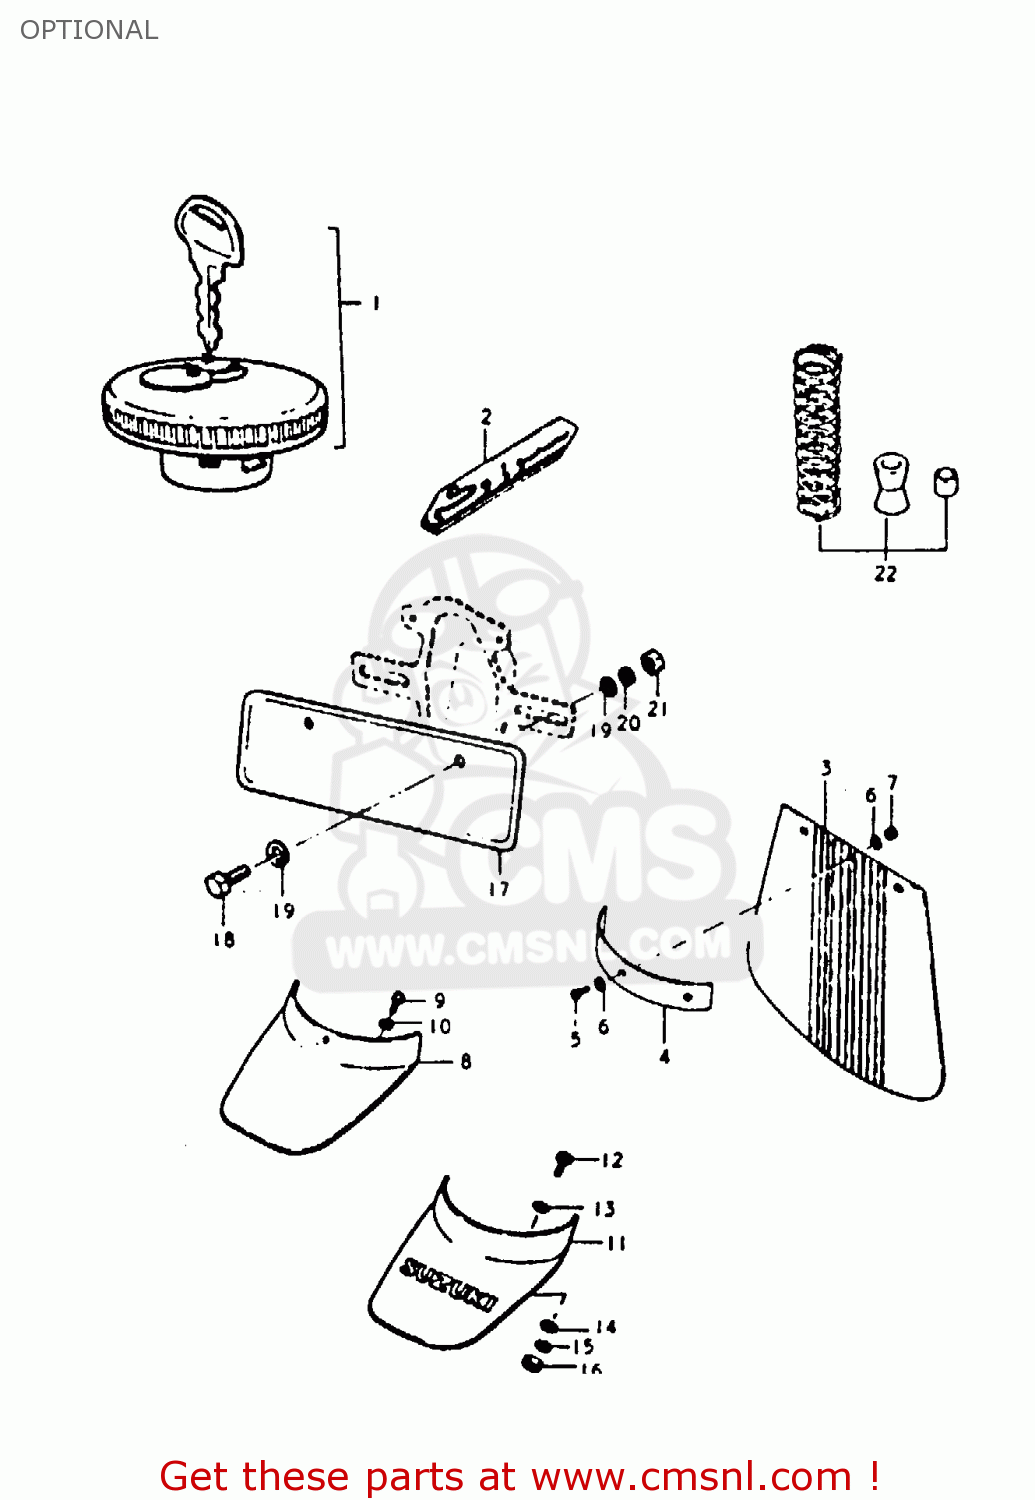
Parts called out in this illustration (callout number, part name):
1	CAP SET,FUEL TANK
2	EMBLEM, FRAME COVER
3	MUD FLAP,FRONT FENDER
4	PLATE,MUDFLAP
5	SCREW 4X10
6	WASHER
7	NUT 4MM
8	PLATE,RR FENDER EXTENSION
9	BOLT
10	LOCK WASHER
17	PLATE,RR LICENSE
18	BOLT
19	WASHER
20	LOCK WASHER
21	NUT
22	SPRING SET,REAR SHOCK ST
